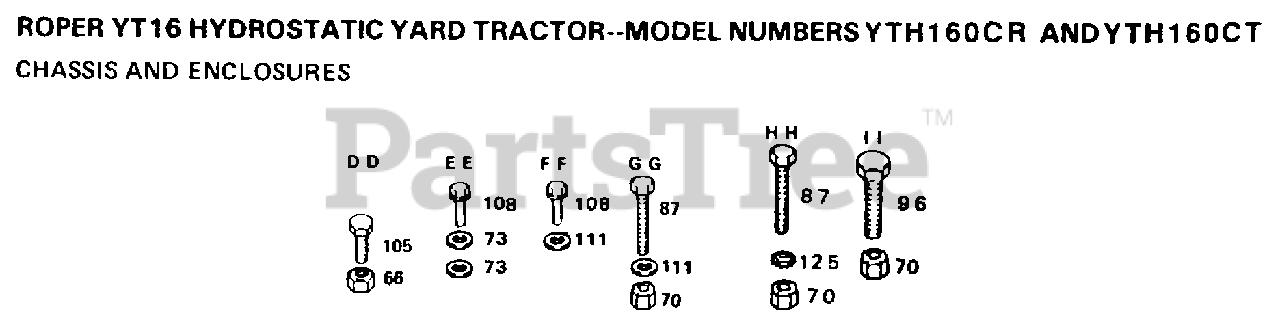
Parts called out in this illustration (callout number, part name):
73	WASHER
87	BOLT
108	SCREW GTV
111	WASHER HYT
125	LOCKWASHER
